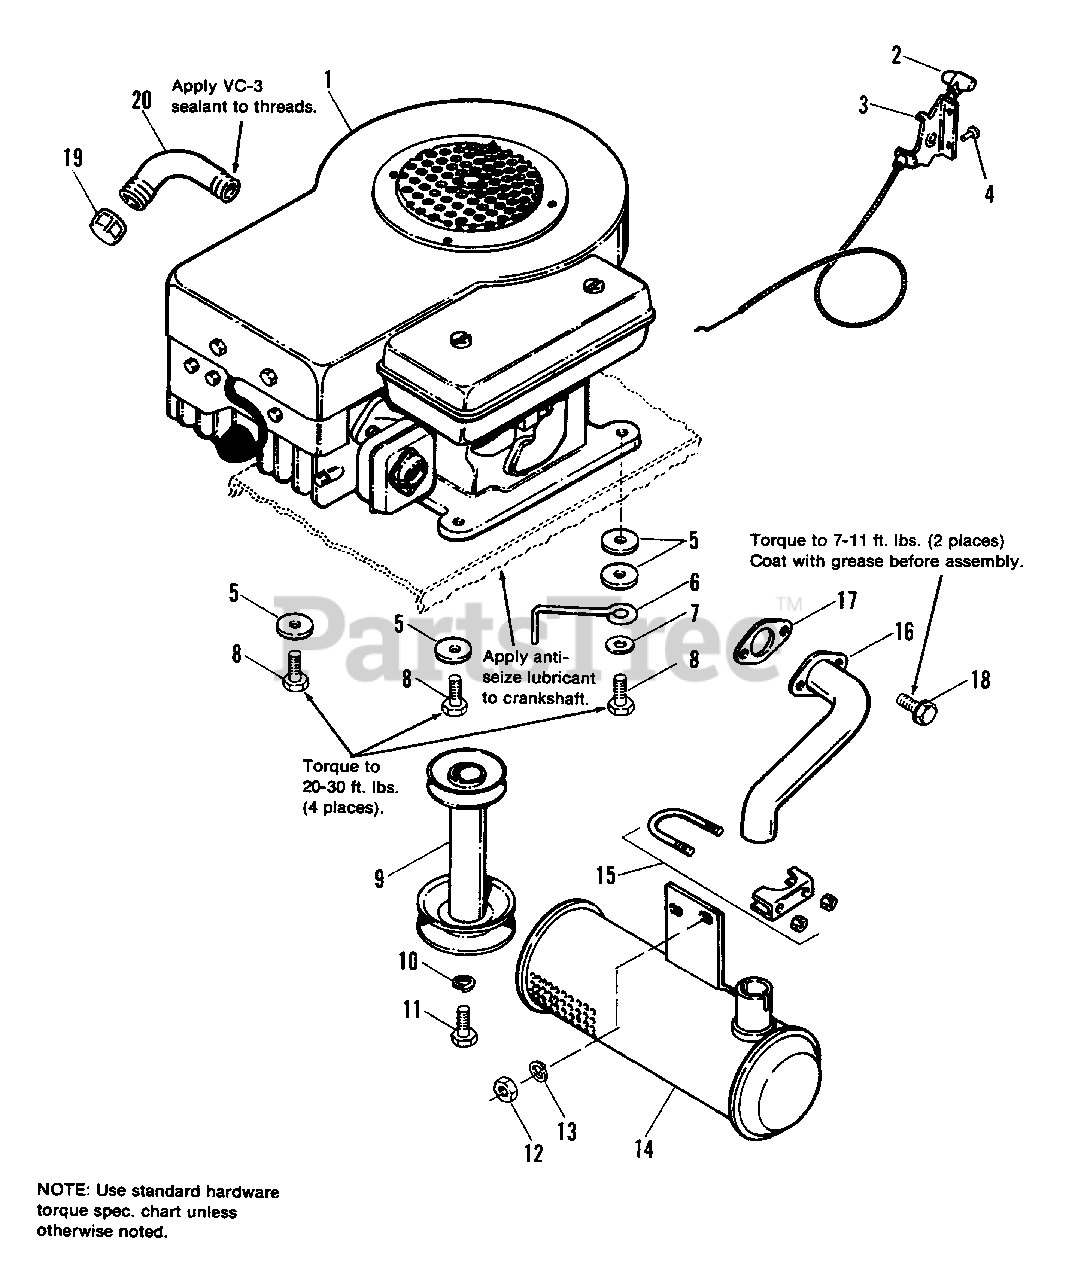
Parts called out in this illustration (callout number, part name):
1	ENGINE, 8 H.P. Briggs & Stratton
1	ENGINE, 11 H.P. Briggs & Stratton
2	KNOB, Throttle
3	CONTROL ASSY., Throttle
4	RIVET, Pop, 1/4
5	WASHER, Plain, 3/8
7	WASHER, 3/8
8	SCREW, Taptite, 3/8-16 x 1-1/2
9	PULLEY ASSY., Engine
10	LOCKWASHER, 7/16
11	CAPSCREW, Hex, 7/16-20 x 1-1/4
12	NUT, Hex, 5/16-18 (1690458 only)
13	LOCKWASHER, 5/16 (1690458 only)
14	MUFFLER (1690458 only)
15	CLAMP ASSY., Exhaust (1690458 only)
16	PlPE, Exhaust (1690458 onIy)
17	GASKET, Muffler (1690458 only)
18	SCREW, Whizlock, 5/16-18 x 3/4 (1690458 only)
19	CAP, Pipe, 3/8
20	PIPE, Oil Drain
